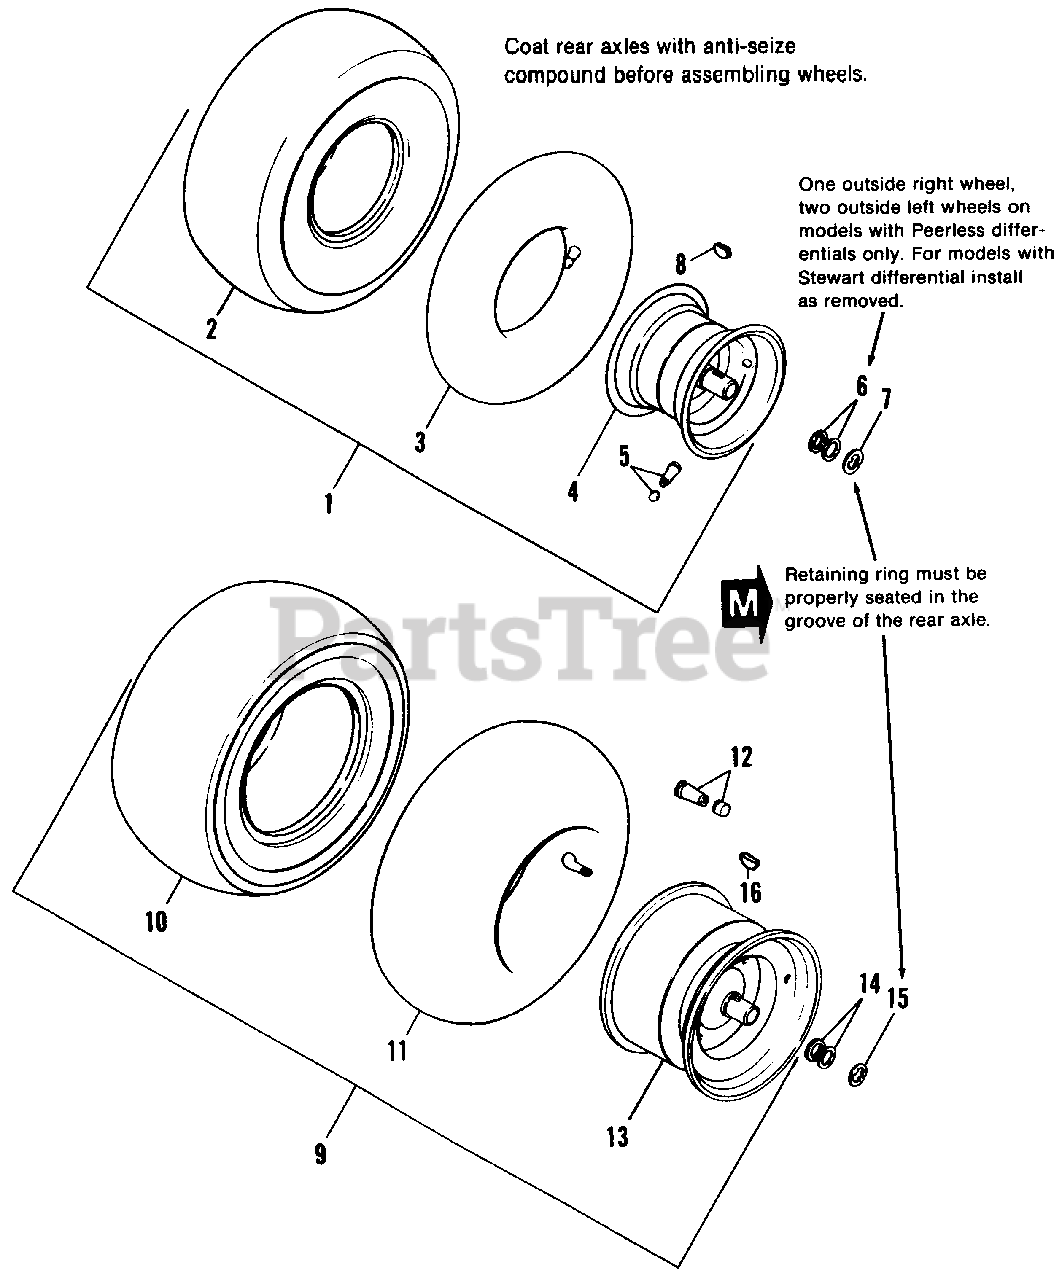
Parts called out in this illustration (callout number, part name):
1	WHEEL & TIRE ASSY., 15 x 6.00-6
2	TIRE, Turf (Carlisle)
2	TIRE, Turf (Goodyear)
3	TUBE (See note below.)
4	WHEEL ASSY. (Later Model)
4	WHEEL ASSY. (Early Model)
5	VALVE STEM & CAP
6	WASHER, Flat
7	E-RING, Retaining, 3/4
8	KEY, 3/16 x 3/16 x 1-1/2
9	WHEEL & TIRE ASSY., 16 x 6.50 8
10	TIRE, Tubeless
11	TUBE (See note below.)
12	VALVE STEM & CAP
13	WHEEL ASSY.
14	WASHER, Plain
15	E-RING, Retaining, 3/4
16	KEY, 3/16 x 3/16 x 1-1/2
